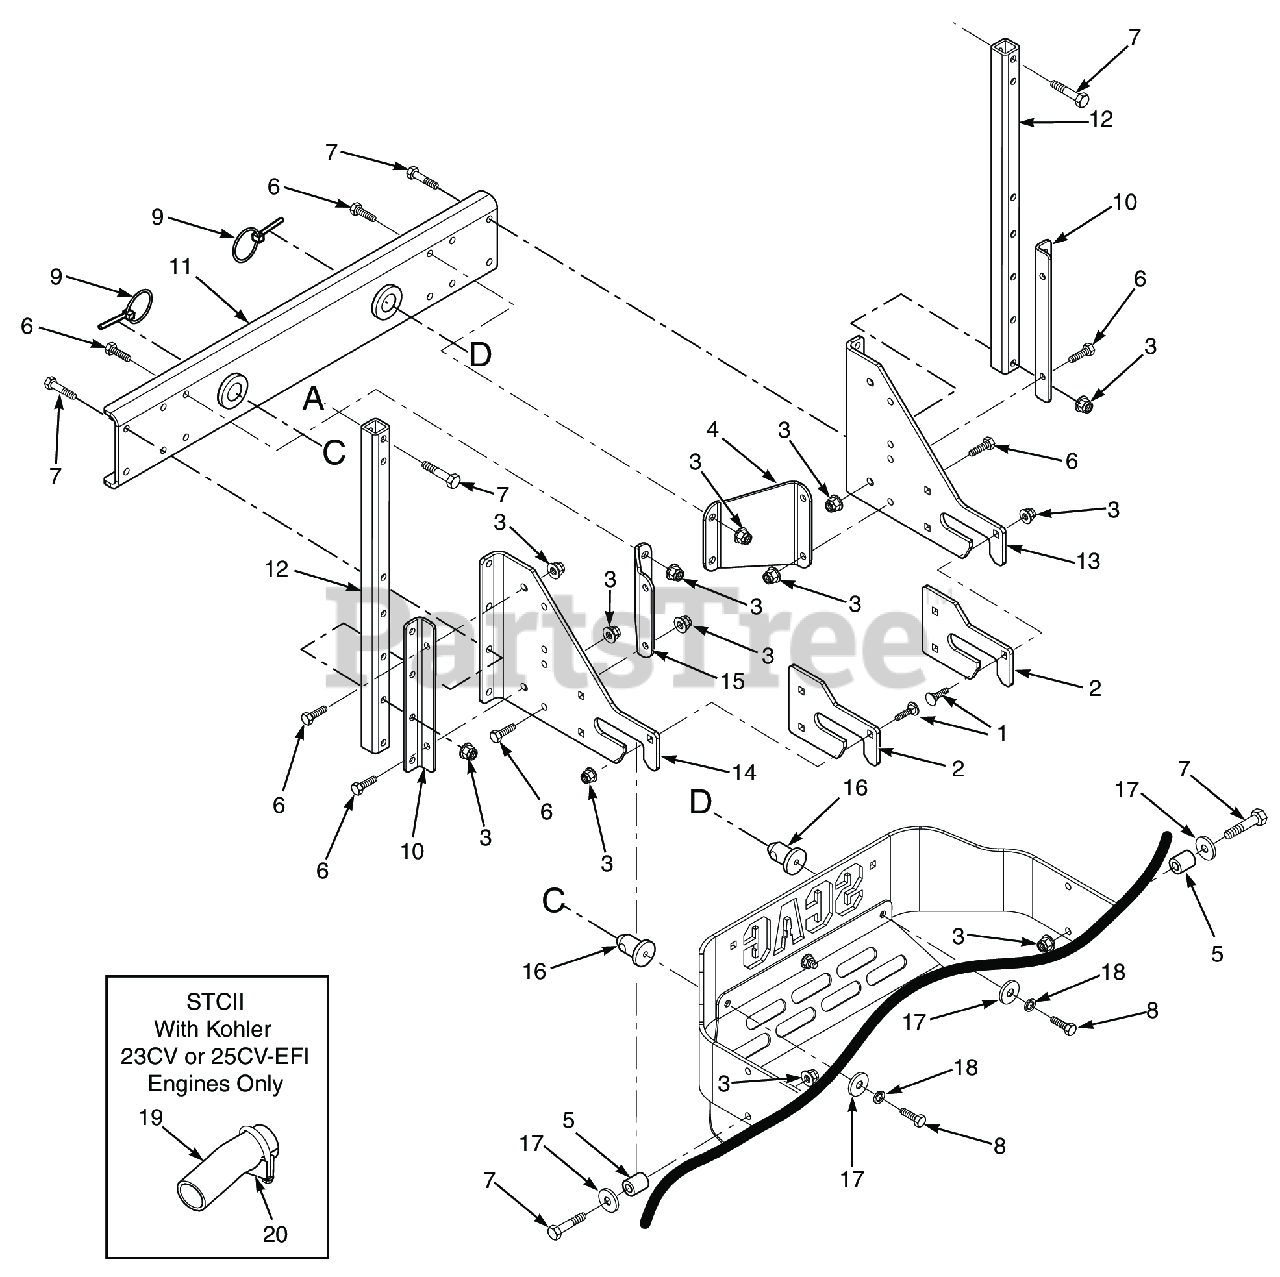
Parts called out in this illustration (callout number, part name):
1	Carriage Bolt, 3/8-16 x 1-1/4"
2	Wear Plate, GC
3	Nut, Flange Elastic Stop Nut, 3/8-16
4	Angle Bracket, GC
5	Spacer
6	Bolt, Hex Head 3/8-16 x 1"
7	Bolt, Hex Head 3/8-16 x 2-1/4" - 61"
8	Bolt, Hex Head 3/8-16 x 1-1/4", Kawasaki FX / FS
9	Quick Pin, 5/16" Dia.
10	Mounting Bracket, Tube
11	Mounting Bracket Weldment
12	Tube, Upright
13	Mounting Bracket, GC R.H.
14	Mounting Bracket, GC L.H.
15	Angle Bracket, GC
16	Pin, GC Locator
17	Flatwasher, 3/8-.406 x 1-1-1/2 x 7 Gauge
18	Lockwasher, 3/8" Spring, Kawasaki FX / FS
19	TUBE, EXHAUST
20	Clamp, Muffler (Clamp Only)
